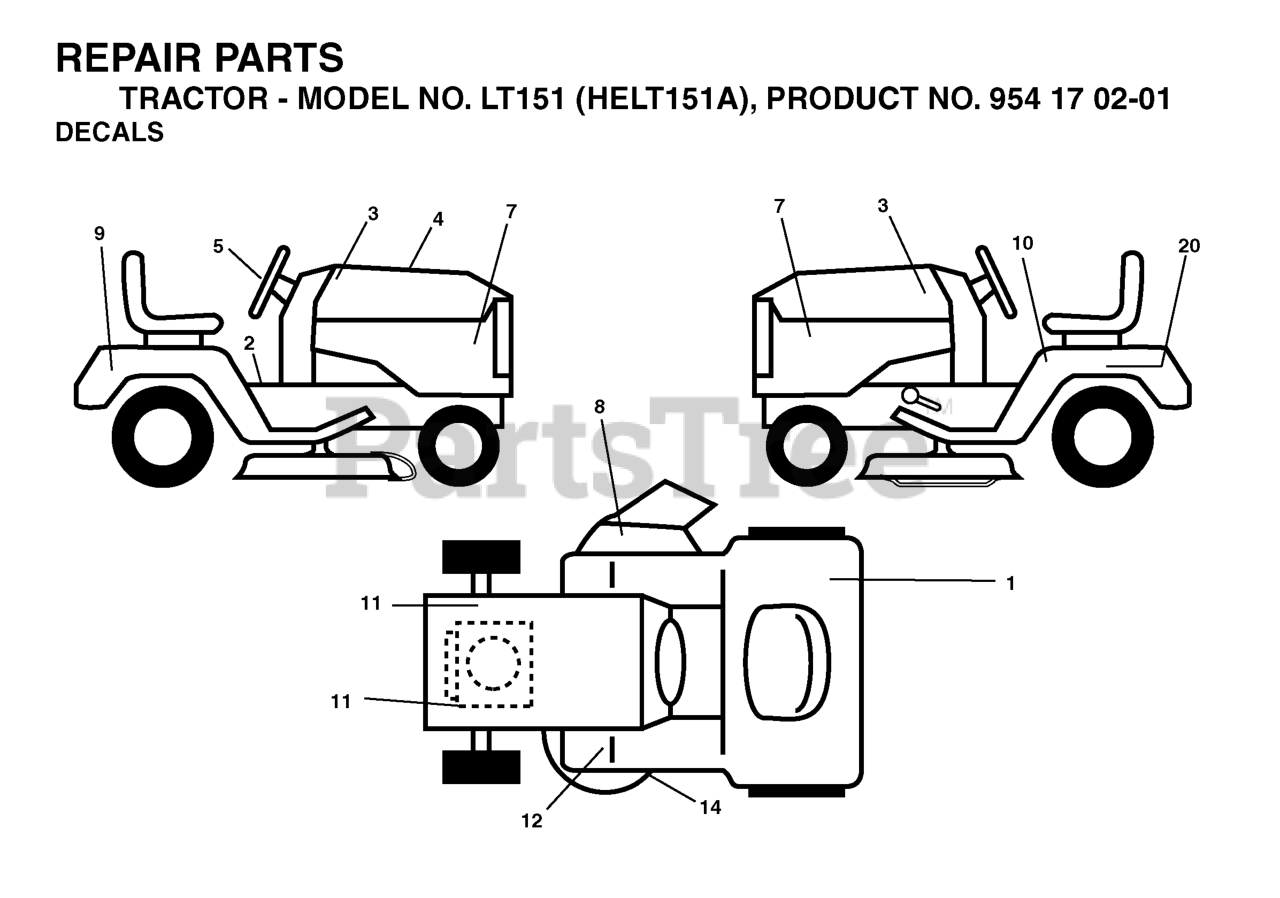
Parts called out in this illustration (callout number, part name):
1	Decal, Fender 100 DB/CE
2	DECAL PARK BRAKE
5	DECAL.STEERING.HUSQ.BLUE
7	DECAL.HOOD.HUSQVARNA.INTERNATI
8	DECAL.INTERNATIONL.CUTFINGER
10	DECAL READ OWNER'S MAN SYMS
12	DECAL
14	DECAL V-BELT SCHEMATIC
20	DECAL BTRY SYMBOLS
